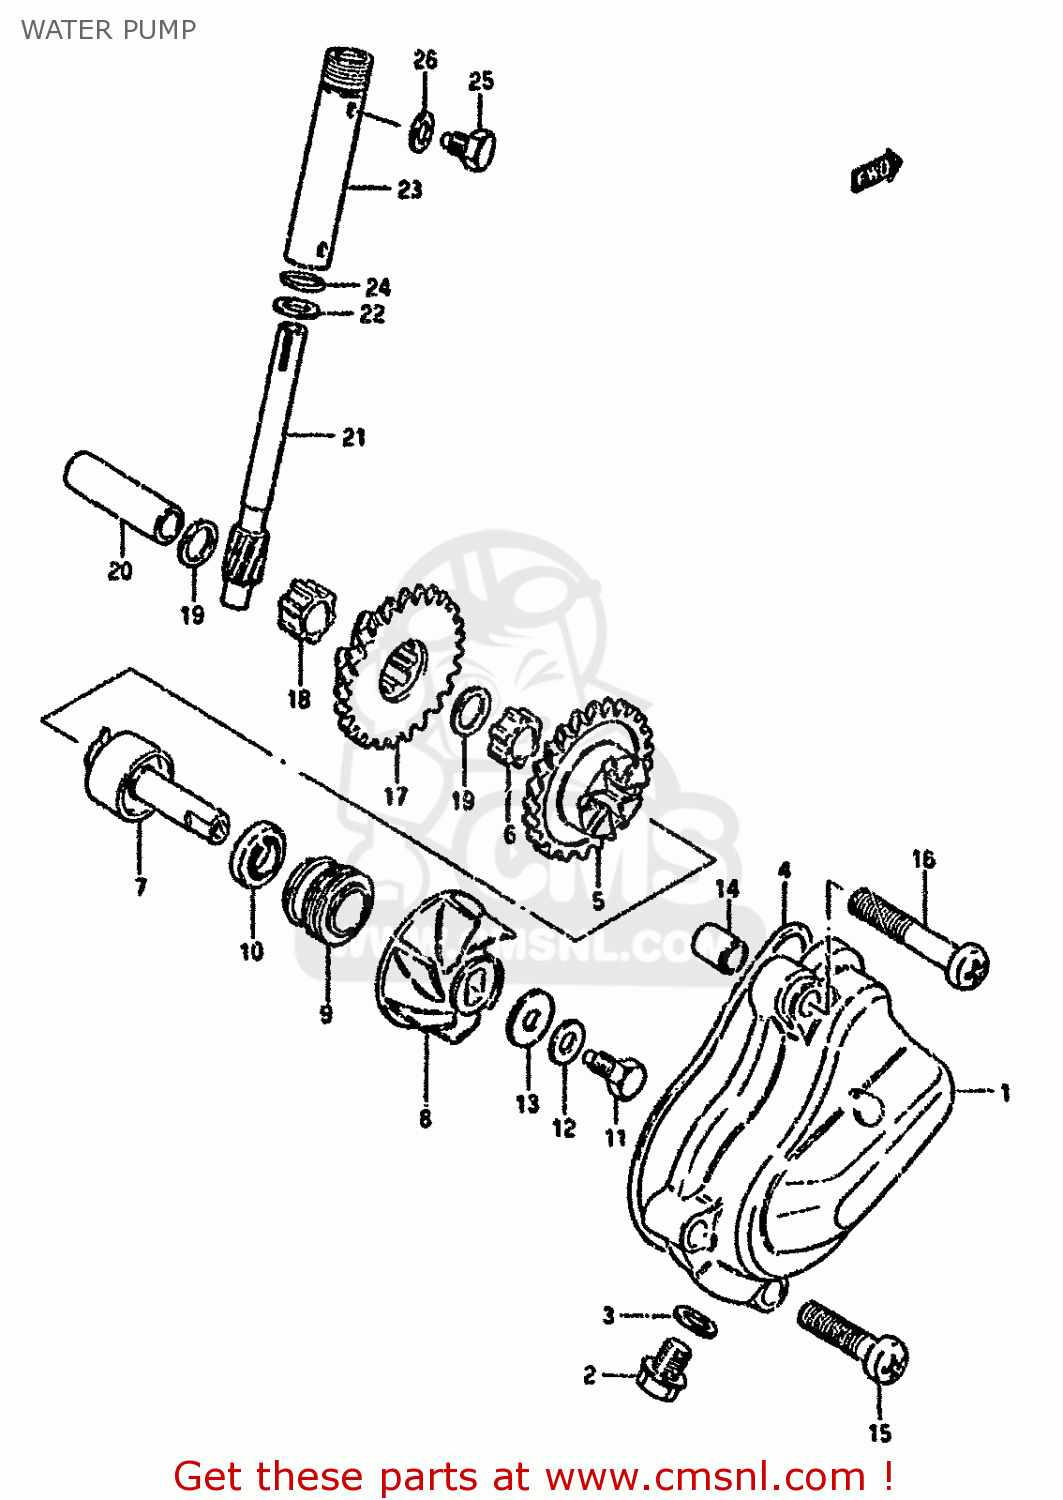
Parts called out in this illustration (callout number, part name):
1	CASE,WATER PUMP
2	BOLT,DRAIN
3	GASKET,DRAIN (NAS)
4	O RING,WATER PUMP CASE
5	GEAR,WATER PUMP DRIVE
6	BUSH
7	SHAFT,WATER PUMP
8	IMPELLER,WATER PUMP
9	SEAL,MECHANICAL
10	SEAL,OIL(10X20X5)
11	BOLT(6X13)
12	WASHER
13	GASKET(6X15X2.2) (NAS)
14	PIN
15	SCREW
16	SCREW
17	GEAR,TACHOMETER DRIVE
18	BUSH,TACHOMETER DRIVE GEAR
19	SHIM
20	SHAFT,TACHOMETER DRIVEN GEAR
21	GEAR,TACHOMETER DRIVEN(NT:10)
22	WASHER(8X13.7X1)
23	SLEEVE,TACHOMETER DRIVE GEAR
24	O RING(D:1.3,ID:9.6)
25	BOLT
26	GASKET(6.2X11X1).2 (NAS)
